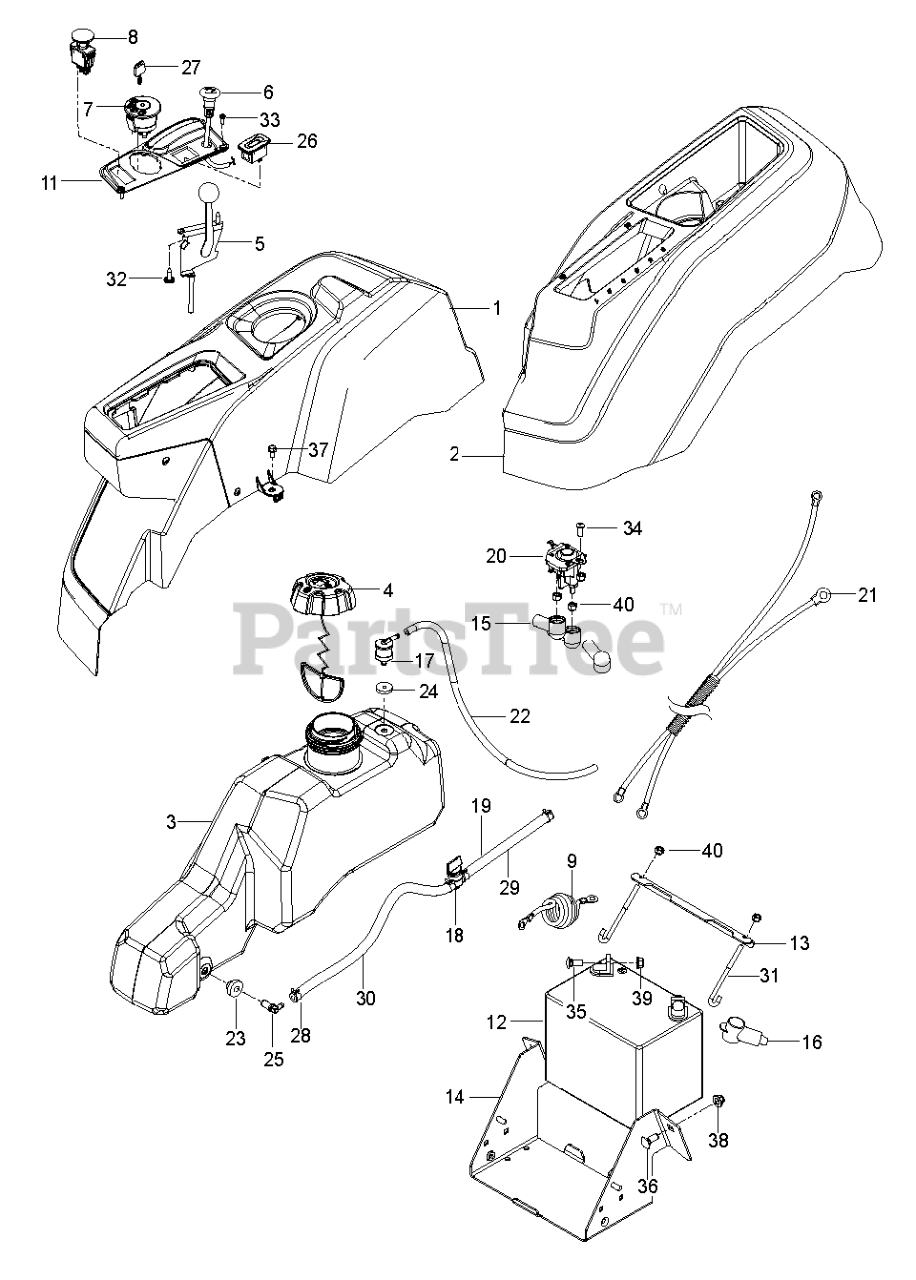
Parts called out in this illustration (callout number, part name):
1	CONSOLE.ASSY.RZ.REFRESH.RH
2	CONSOLE.LH.ASM
3	TANK.ASM3"NECK.NOCAP.NOSHDRZ18
4	FUEL CAP
4	CAP ASSY FUEL 3" GRAY
5	THROTTLE CABLE
6	CHOKE.PUSH-IN.STYLE
7	RP IGNITION SWITCH
8	RP SWITCH.PTO.TERMINAL.STD.RED
9	CABLE BATTERY POS RZ
11	CONTROL.PANEL.RZ.REFRESH.RH
12	BATTERY WET NOT SELLABLE
13	BRACKET.PNT.MOUNT.BATTERY.EDIP
14	BOX.PNT.BATTERY.RZ.EDIP
15	TERMINAL COVER
17	VALVE.FUEL.CHECK
18	FUEL VALVE
19	FUEL.HOSE.SHUT.OFF.ASM.10".18"
20	SOLENOID.STARTER.BRASS.PLUNGER
21	HARNESS.BTTRY.CABLE.RZ.REFRESH
22	HOSE.3/16".VAPOR.LINE.50"LGTH
23	BUSHING OUTLET T
24	GROMMET.ROV.SENTEC
25	STEM FUEL TANK
26	GUAGE.SRVCMNDR.HRMTR.
27	KEY.CHAIN.BLISTER.PACK.GEN.USA
28	HOSE CLAMP
29	HOSE.1/4".LOW.PERM.FUEL.LN.10"
30	HOSE 1/4" LOW PERMEATION FUEL
31	HOOK.J.BATTERY
32	SCREW.PAN.HEAD.#10
33	SCREW 6-19X.437
34	SCR 1/4-20 X 5/8 BTN SKT HD ZD
35	BOLT 5/16C X 3/4" CARRIAGE
36	RHSNB 3/8C X 1
37	SCREW
38	NUT 3/8-16 HEX FLG NYLOC ZD
39	5/16-18 NYLOC FLANGE NUT
40	NUT.1/4-20.HEX.NYLOC.ZD
